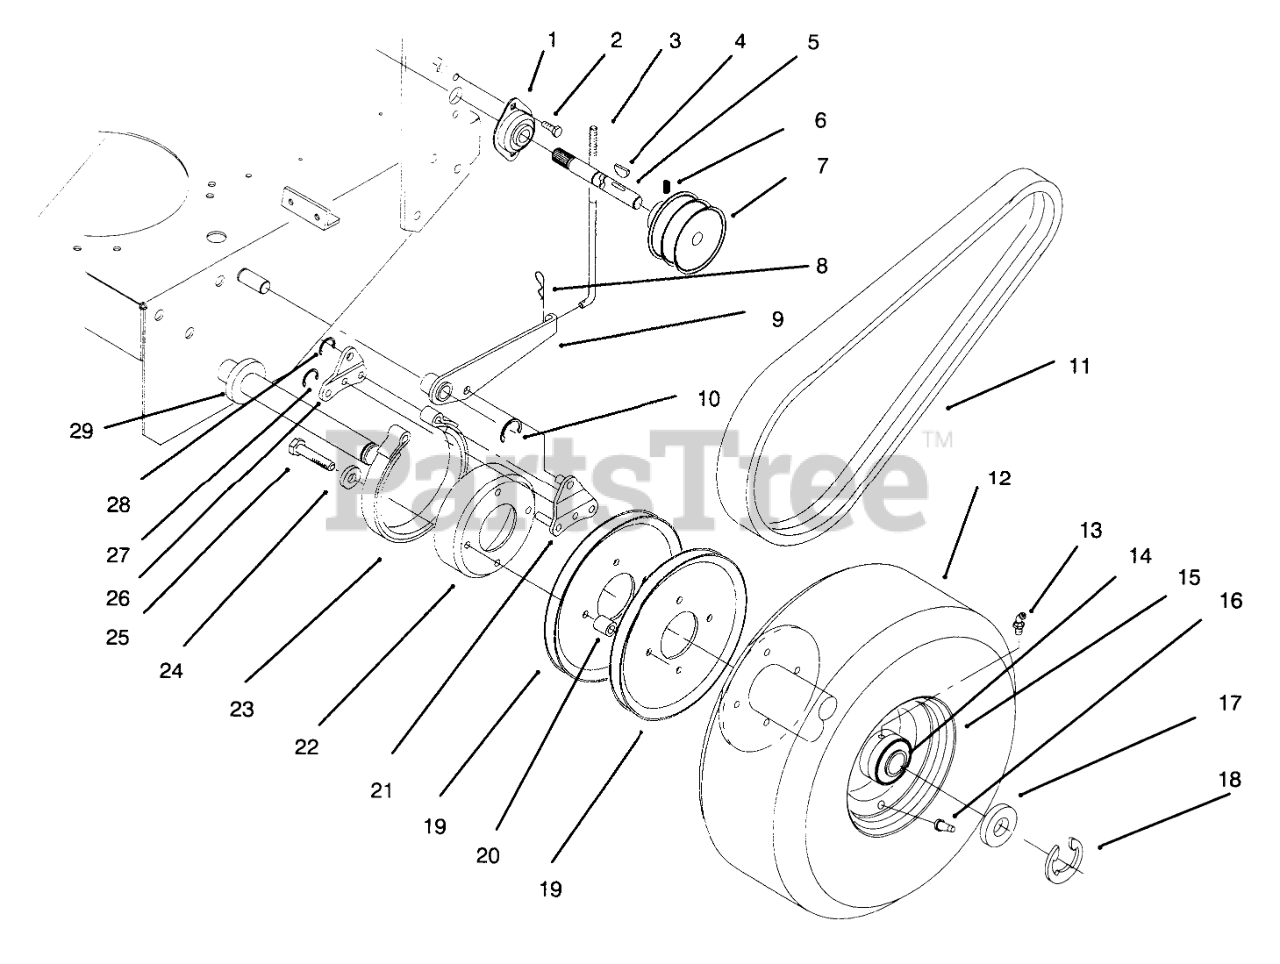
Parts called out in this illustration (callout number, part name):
1	BEARING-EXTERNAL SHAFT
2	SCREW-HH
3	ROD-BRAKE
4	KEY-WOODRUFF
5	SHAFT-EXTENSION, RH
6	SCREW-SET, HS
7	Pulley-Drive
8	PIN-COTTER
9	Brake Arm-LH
10	RING-RETAINING
11	V-BELT
13	FITTING-LUBE, 45 DEG
14	BEARING-BALL
15	WHEEL AND HUB ASM
16	STEM-VALVE
17	WASHER-THRUST
18	RING-RETAINING
19	Pulley-Wheel
20	SPACER-PULLEY
21	LINK-Brake
22	Drum-Brake
23	BAND-BRAKE
24	WASHER-LOCK
25	SCREW-HH
26	Plate-Link
27	RING-RETAINING
28	RING-RETAINING, EXTERNAL
29	WASHER-WHEEL
